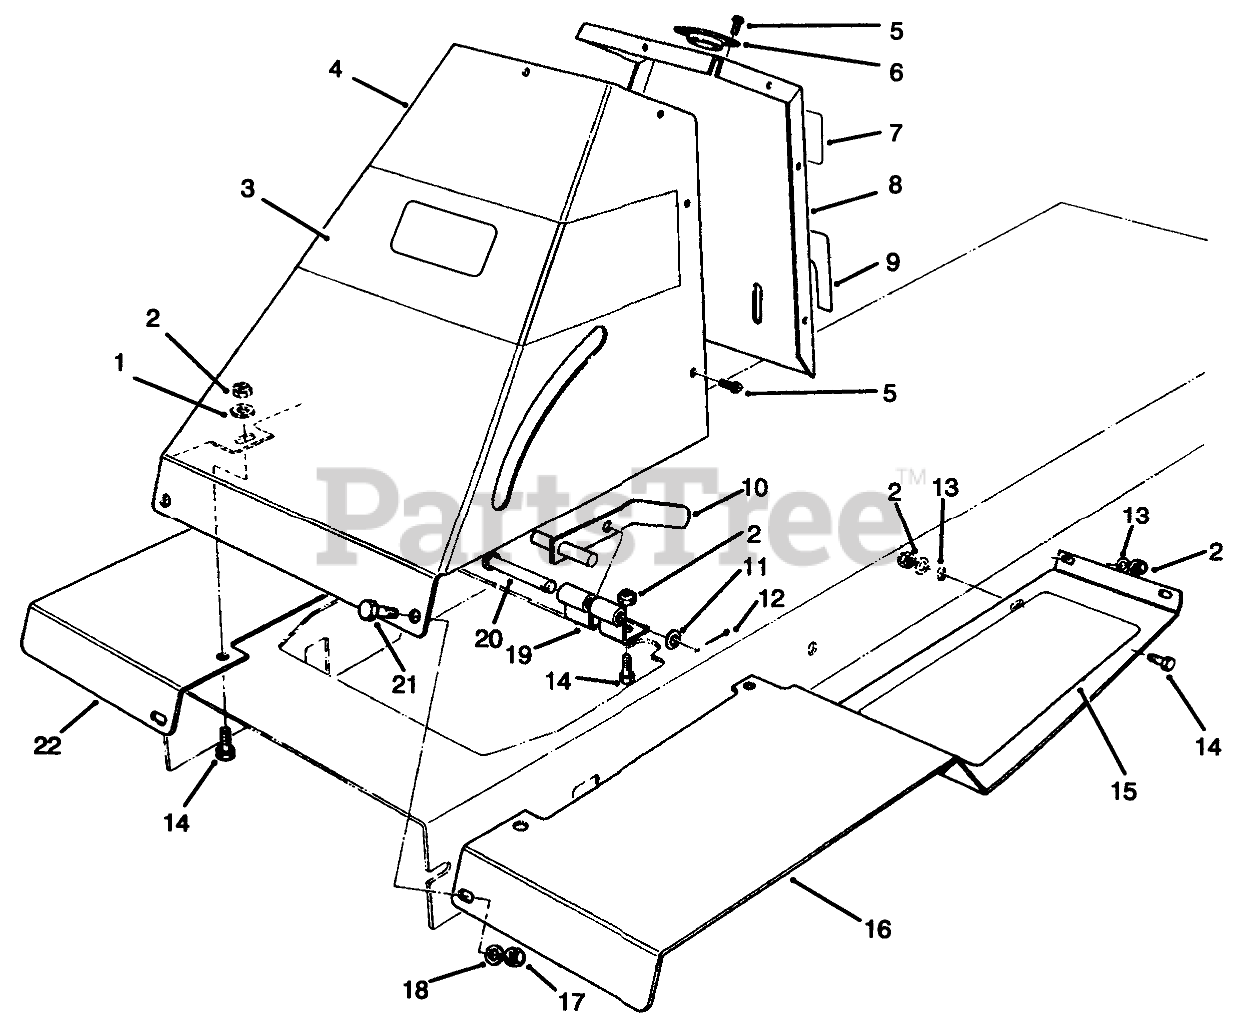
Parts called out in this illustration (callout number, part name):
1	WASHER-FLAT
2	NUT-LOCK, NI
3	DECAL - STEERING SUPT
4	Tower-Front
5	SCREW-HWHTF
6	GUIDE-STRG SHAFT
7	DECAL-DANGER
8	Tower-Rear
9	PARK BRAKE DECAL
10	PARKING BRAKE WA B
11	WASHER-FLAT
12	PIN-COTTER
13	WASHER-PLAIN
14	SCREW-HH
15	TREAD-L.H. FOOT
16	Footrest-LH
17	NUT-LOCK, NI
18	WASHER-FLAT
19	Bracket-Parking Brake
20	PIN-CLEVIS
21	SCREW-HH
22	Footrest-RH.
